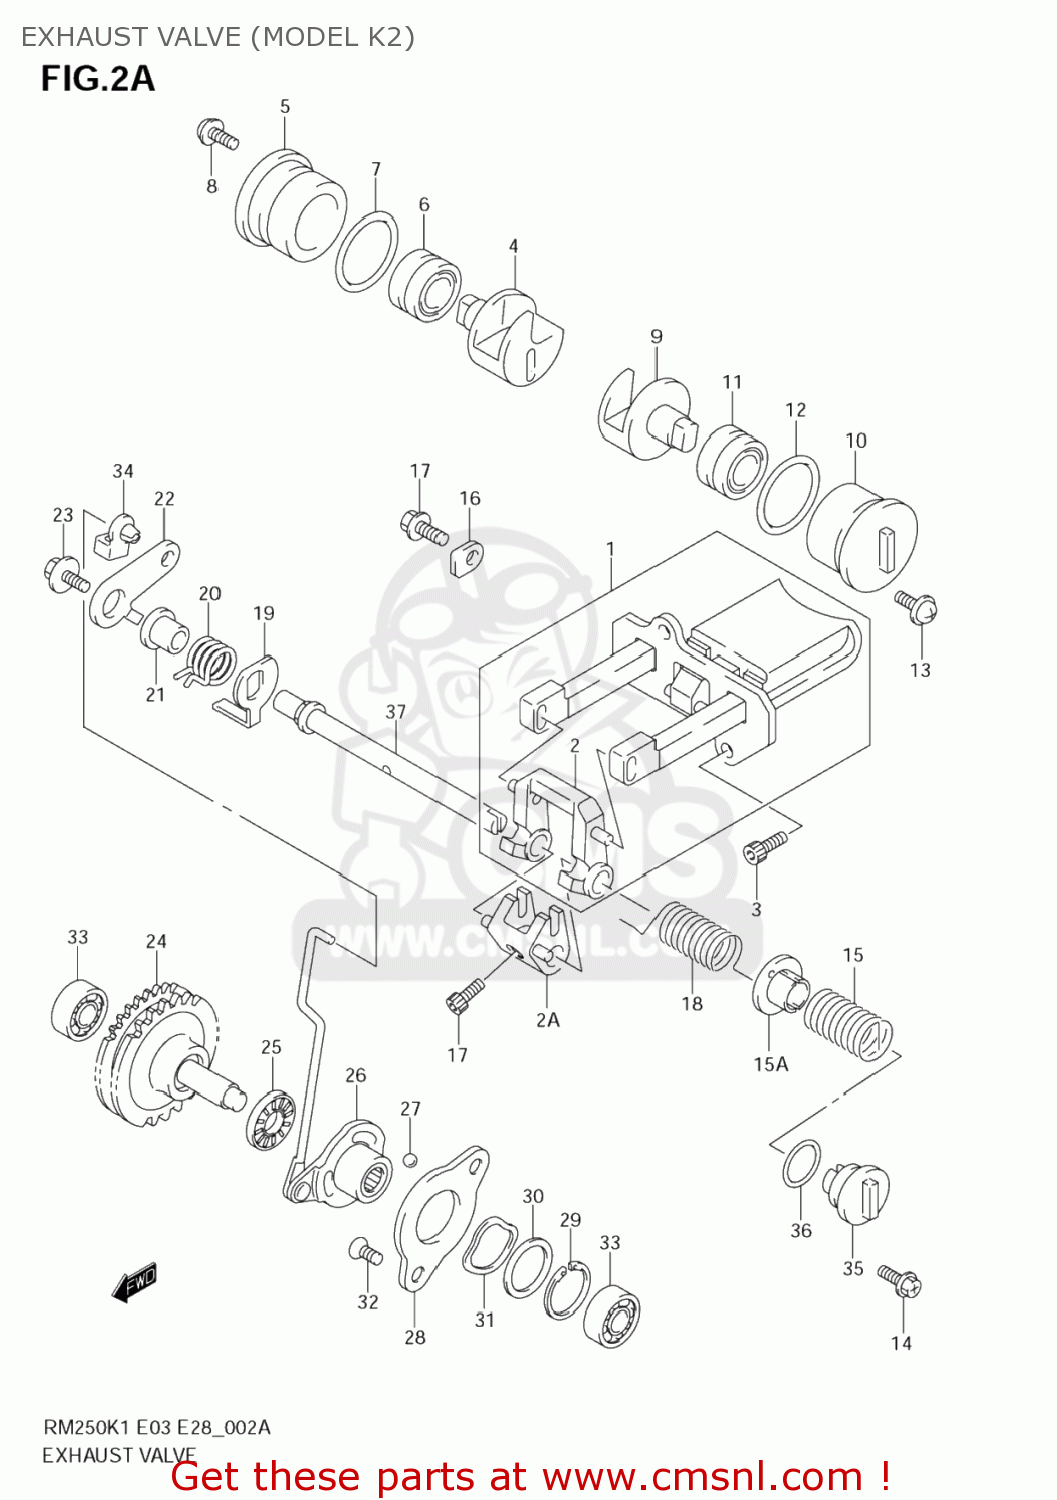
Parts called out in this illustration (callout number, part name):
1	VALVE ASSY,EXHAUST MAIN
2	VALVE,EXHAUST MAIN
2A	ARM,EXHAUST VALVE
3	BOLT
4	VALVE,EXHAUST SIDE,R
5	CAP,EXHAUST SIDE VALVE
6	BEARING(12X24X13)
7	O RING(D:1.9,ID:28.3)
8	SCREW 5X12
9	VALVE,EXHAUST SIDE,L
10	CAP,EXHAUST SIDE VALVE
11	BEARING(12X24X13)
12	O RING(D:1.9,ID:28.3)
13	SCREW 5X12
14	BOLT
15	SPRING,EXHAUST VALVE SHAFT
15A	SPACER,EXHAUST VALVE SHAFT
16	RETAINER
17	BOLT
18	SPRING,EXHAUST SIDE
19	LEVER,EXHAUST VALVE NO.2
20	SPRING
21	SPACER,EXHAUST VALVE
22	LEVER,EXHAUST VALVE NO.1
23	BOLT(5X12)
24	GOVERNOR ASSY,EXHAUST VALVE
25	BEARING(10X22X2.8)
26	ACTUATOR,EXHAUST VALVE
27	BALL
28	STARTER,EXHAUST VALVE ACTUATOR
29	CIRCLIP
30	SHIM(19.1X25X0.3)
31	WASHER
32	SCREW(5X10)
33	BEARING(8X22X7)
34	BUSH,EXHAUST VALVE ROD NO.1
35	CAP,EXHAUST VALVE SHAFT SPRING
36	O RING(D:1.9,ID:14.5)
37	SHAFT,EXHAUST VALVE
